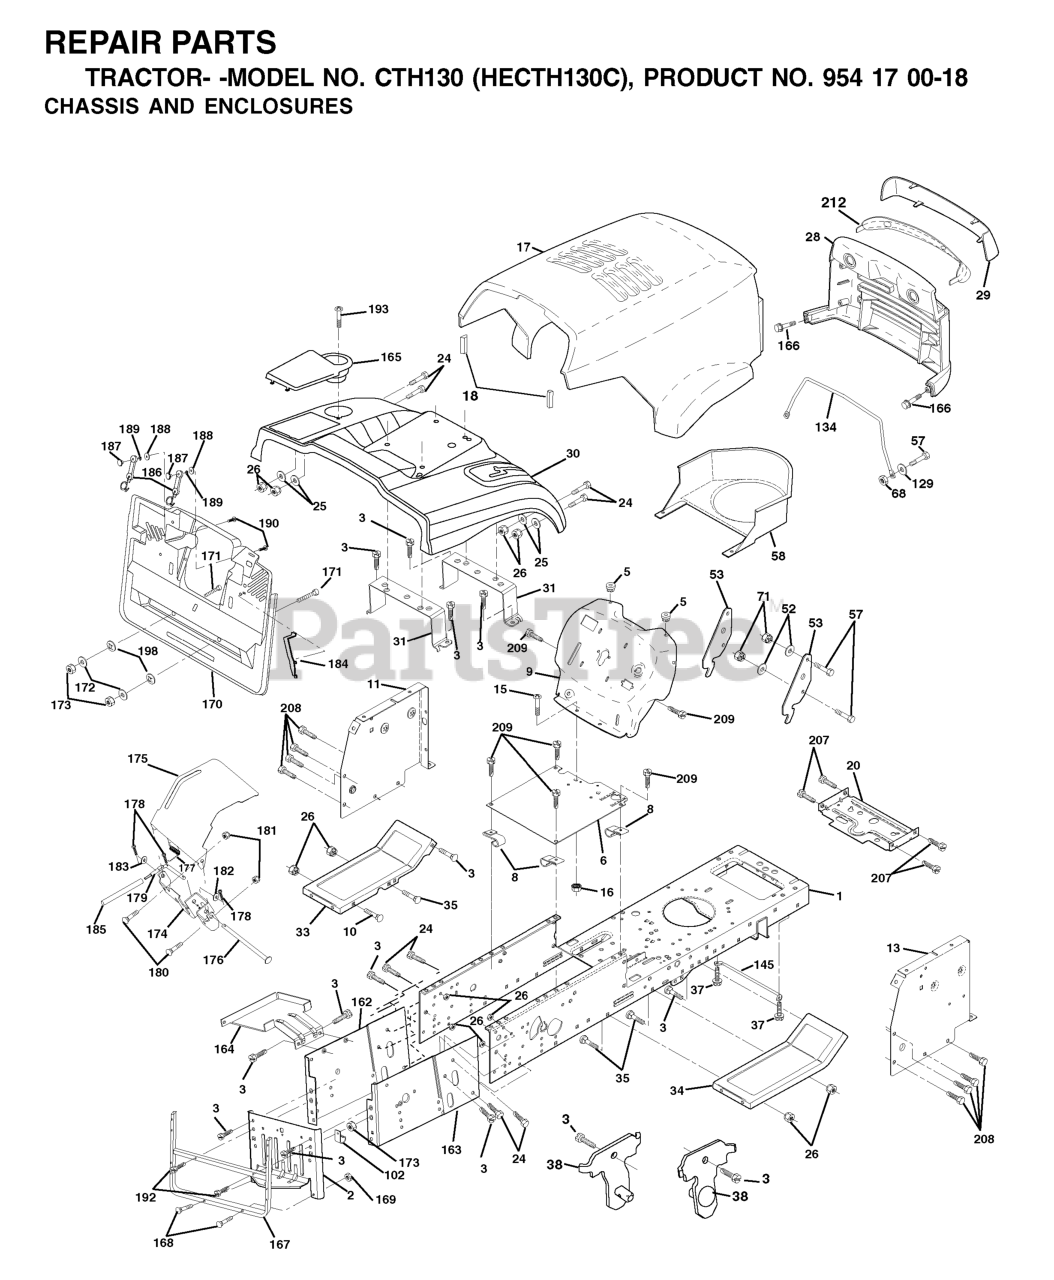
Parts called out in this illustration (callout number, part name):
1	CHASSIS STAMPING
3	SCREW 3/8-16X3/4
5	BUMPER.RUBBER.HOOD
6	SADDLE FLAT
8	CLIP,INSULATOR
10	BOLT D
11	PANEL DASH LH
13	DASH PANEL RH
15	Screw, Machine, Truss Head 5/16-18 UNC x 3/4
16	NUT
17	HOOD
18	BUMPER HOOD T
20	PLATE MTG
25	WASHER
26	NUT
28	GRILL
29	LENS
30	FENDER.CRD.ORANGE
31	BRACKET SUPPORT FENDER
33	FOOT REST LH
34	FOOTREST RH
37	Screw 5/16-18 x 1/2 Hex, Self Tapping 5/16-18 x 1/2
38	BRACKET
53	BRACKET PNT PICK OFF LT/PL
57	BOLT
58	AIR DUCT P/L/LT
68	NUT
71	NUT.CROWNLOCK.1/4
102	CLIP T
134	ROD SUPPORT HOOD LT/PL HUS.
145	ROD PIVOT CHASSIS/HOOD
162	Bracket Exten Chassis Lh CRD
165	COVER BATTERY
166	SCREW
167	SUPPORT.ASM.BACKPLATE
168	BOLT.ROUND.HEAD.SQUARE.NECK
169	NUT T
170	BACKPLATE ASM
171	Bolt Hex 3/8-16 x 2-1/2 Gr. 5
172	WASHER
176	HINGE PIN
177	SPRING COVER LH
178	COTTER PIN
180	BOLT RB
181	LOCKNUT
183	WASHER
184	BRACKET.ACTUATOR.BAGGER.SRD
185	TUBE LEVER
186	LATCH ASSY
187	WELDNUT
189	LOCKWASHER #10
190	SCREW
192	SCREW LT
193	Screw Truss 1/4-20 x 3/4 Tap/R
207	SCREW, 5/16-18 X 1/2
208	SCREW 3/8-16X1/2
209	SCREW, 3/8-16X3/4
212	INSERT LENS REFLECTOR
